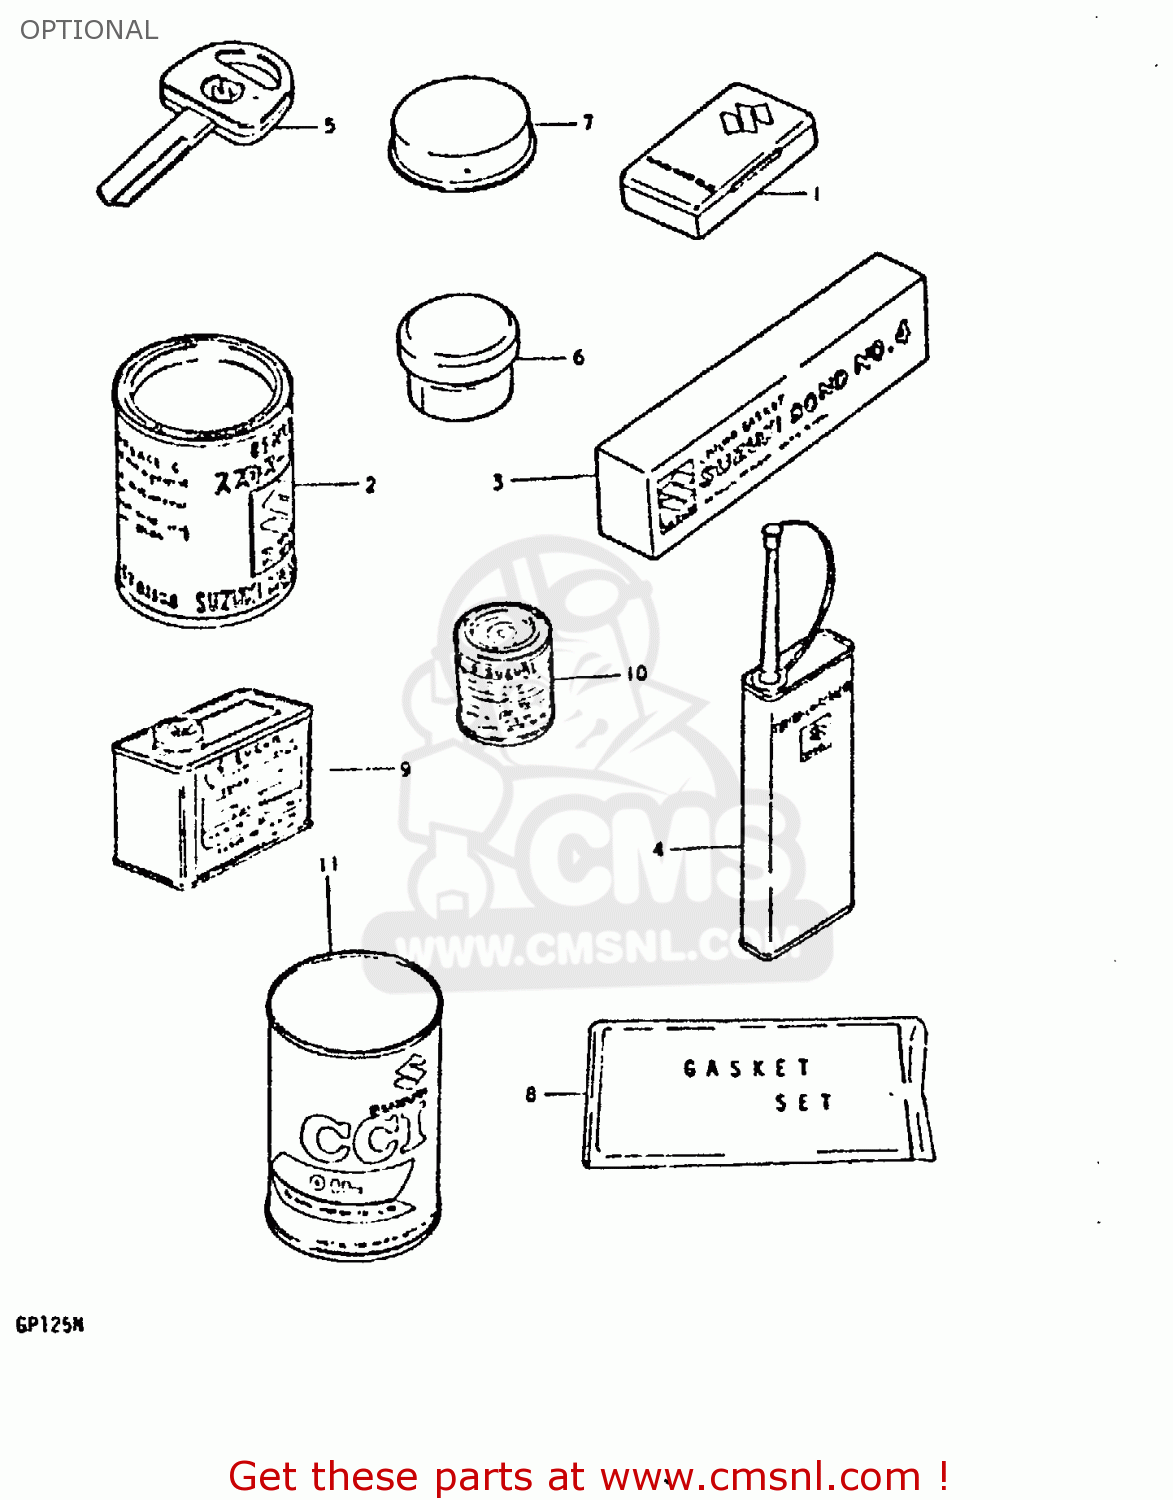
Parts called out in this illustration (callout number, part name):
1	TUBE REPARING TOOL
2	GREASE(C)EP2 LITHIUM 150G
3	BOND 1104
4	THREAD LOCK NO.1401 CLEAR 200G
5	KEY,BLANK
8	GASKET SET
9	PAINT (BLACK)
10	PAINT,BLACK
11	CCI OIL
